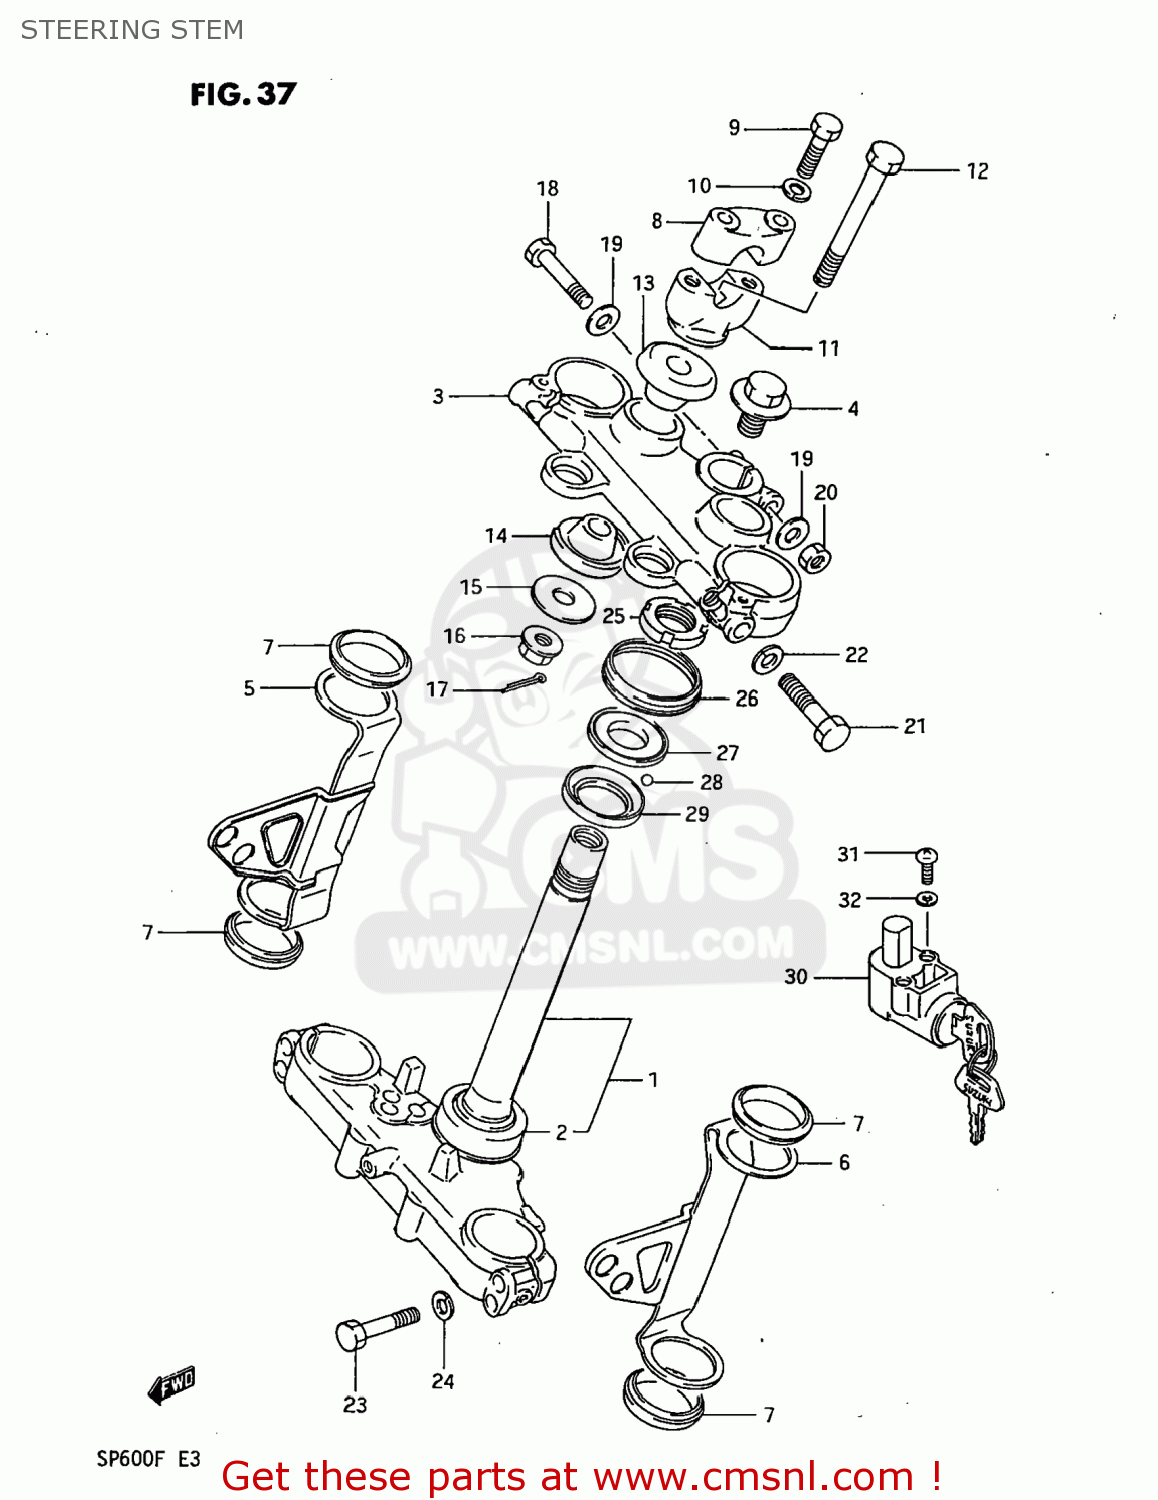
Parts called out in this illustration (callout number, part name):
1	STEM,STEERING
2	BEARING
3	HEAD,STEERING STEM
4	BOLT,STEERING STEM
5	COVER,FORK,RIGHT
6	BRACKET,HEADLAMP,LEFT
7	CUSHION,HEAD LAMP BRACKET
8	HOLDER,HANDLEBAR
9	BOLT
10	LOCK WASHER
11	HOLDER,HANDLE LWR
12	BOLT,HANDLE HOLDER
13	DAMPER,UPR
14	DAMPER,LWR
15	WASHER,HANDLEBAR HOLDER
16	NUT
17	COTTER PIN
18	BOLT
19	WASHER
20	NUT ,8MM
21	BOLT
22	LOCK WASHER
23	BOLT
24	LOCK WASHER
25	NUT,STEERING STEM
26	SEAL,STEERING UPR DUST
27	RACE,STEERING,OUTER,UPPER
28	BALL
29	RACE,STEERING,INNER,UPPER
30	LOCK ASSY,STEERING
31	SCREW
32	LOCK WASHER
